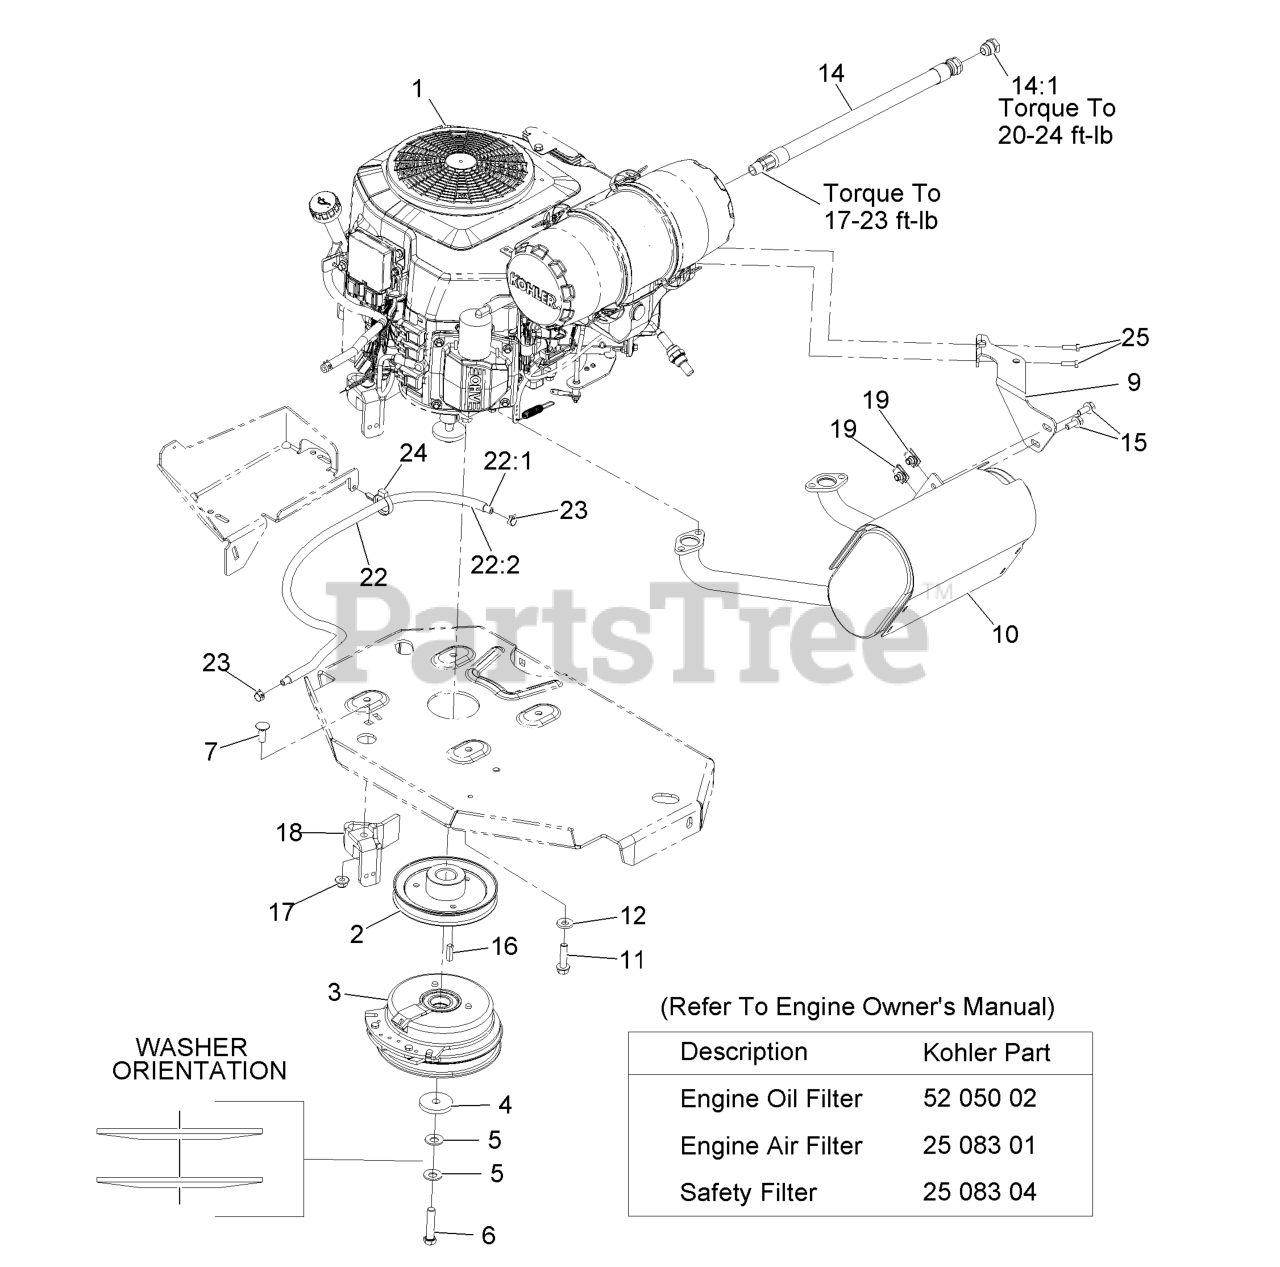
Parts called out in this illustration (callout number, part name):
1	Engine,Koh 29hp Efi
2	SHEAVE
3	CLUTCH KIT
4	WASHER-CLUTCH
5	WASHER-SPRING
6	SCREW-HH W/LOCTITE
7	SCREW-CARR
9	MUFFLER BRACKET KIT
11	SCREW-HWH
12	WASHER-BELLEVILLE
15	SCREW-HHF
17	NUT-HF, NI
18	CLUTCH-ANCHOR
22	FUEL LINE ASM
22:1	HOSE-FUEL
22:2	SLEEVE-THERMAL
23	CLAMP-HOSE
24	CLAMP-HOSE
25	SCREW-HH M6-1 X 20Mm W/Patch
